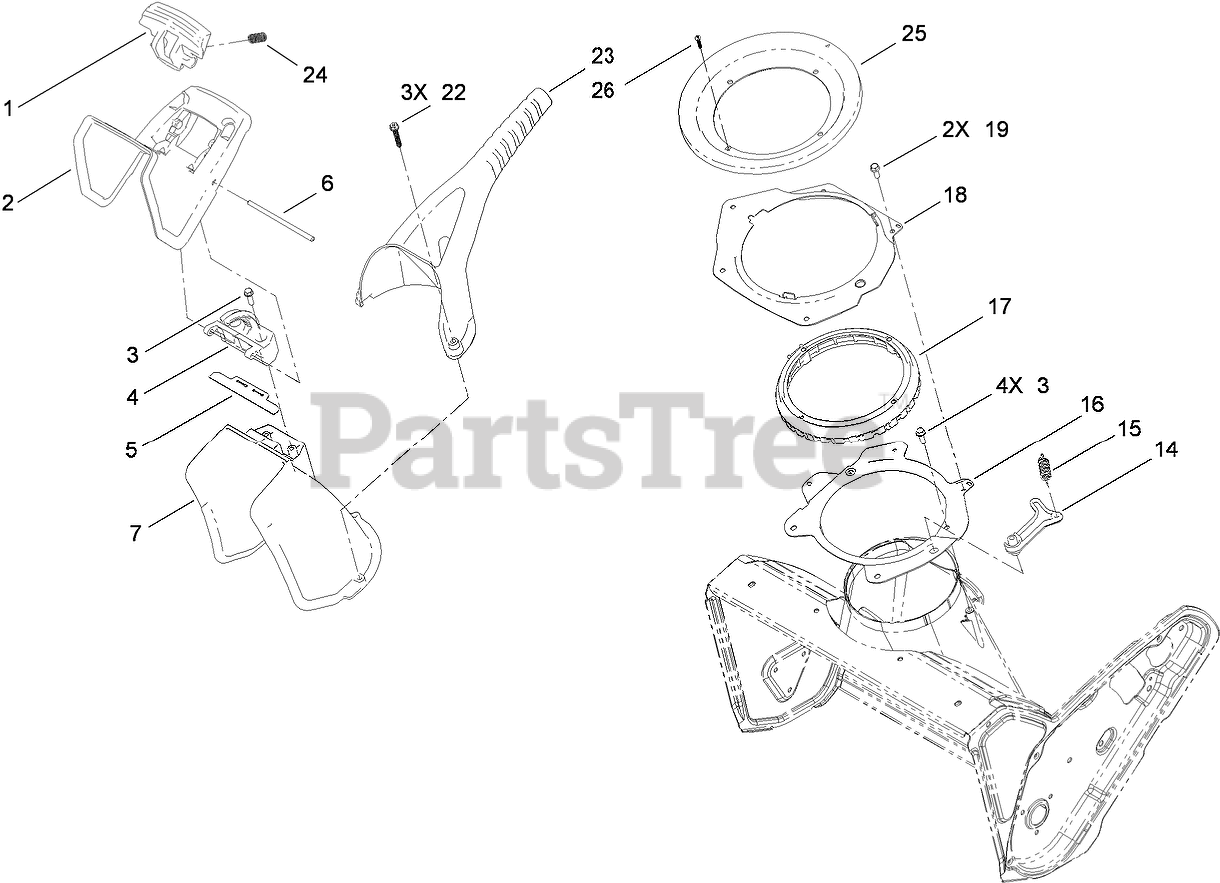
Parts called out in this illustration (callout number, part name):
1	TRIGGER-DEFLECTOR
2	DEFLECTOR-CHUTE, CE
3	SCREW-HWH
4	HINGE-RATCHET, DEFLECTOR
5	SEAL-DEFLECTOR
6	PIN-HINGE, DEFLECTOR
14	PAWL-DETENT
15	SPRING-EXTENSION
16	RING-SUPPORT, CHUTE
17	RING-CHUTE, DETENT
18	RETAINER-RING, CHUTE
19	SCREW-HWH
22	SCREW-HWH, PLASTITE
23	HANDLE-CHUTE
24	SPRING-COMPRESSION
25	SEAL-RING, CHUTE
26	SCREW-PPH
